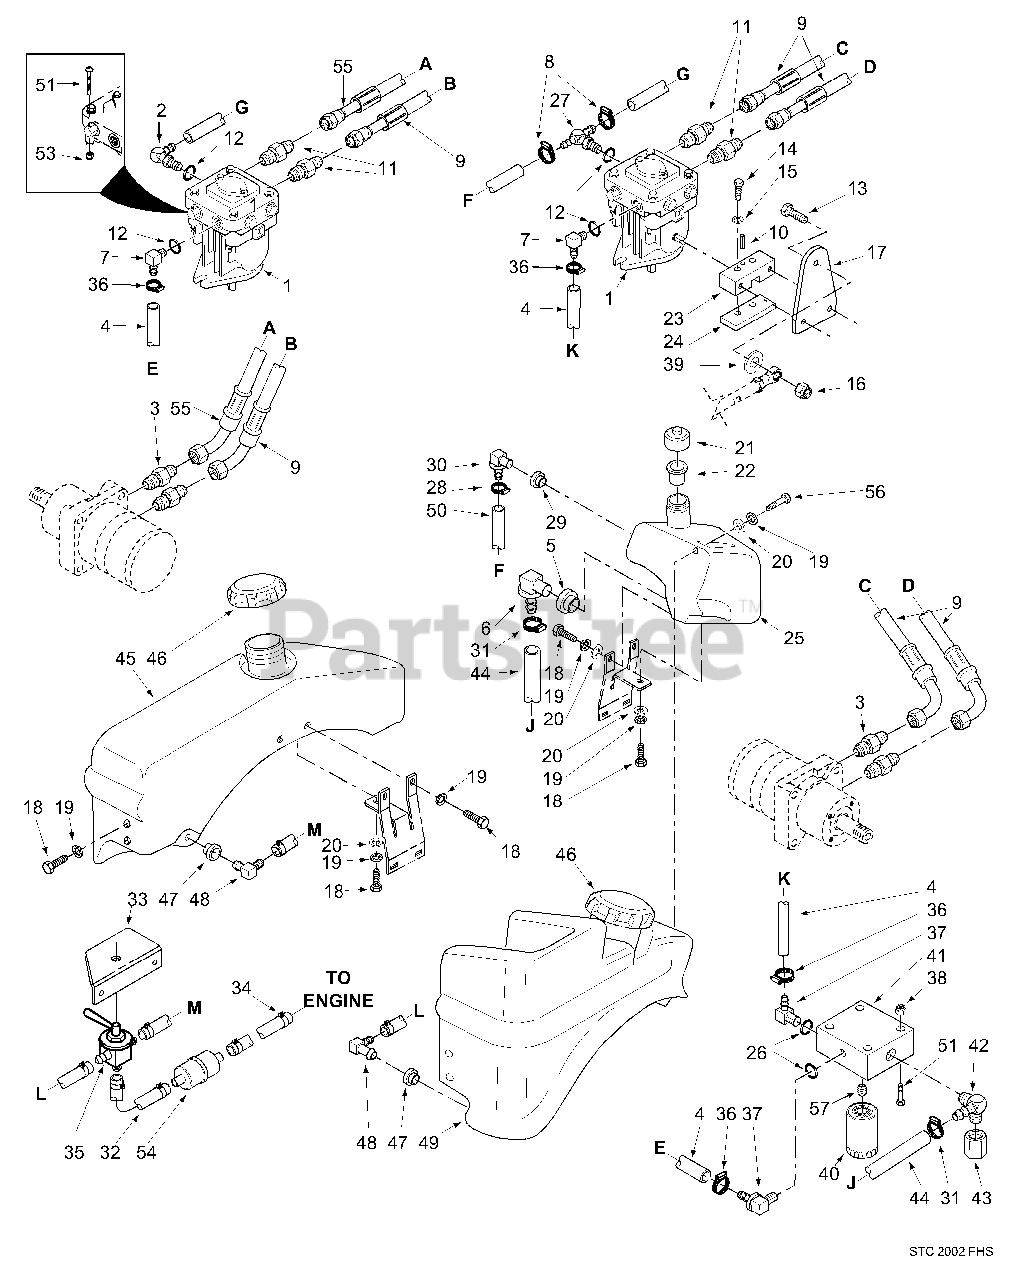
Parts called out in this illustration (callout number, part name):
1	Pump, BDP-10A-316 (L.H.)
2	Elbow, 90 Degree 9/16 O-Ring x 3/8 Hose
3	Fitting, 1/2" JIC x 5/8 O-Ring
4	Hose, 3/8 Pushlock (Specify length)
5	Bushing
6	Fitting
7	Elbow, 90 Degree 9/16 O-Ring x 3/8 Hose
8	Hose Clamp, .69 Dia.
9	Hose Assembly
10	Roll Pin
11	Fitting, 1/2" JIC x 1/2" O-Ring
12	O-Ring
13	Bolt, Hex Head 3/8-16 x 1-1/2"
14	Bolt, Hex Head 1/4-20 x 1-1/4"
15	Lockwasher
16	Nut, Elastic Stop 3/8-16
17	Control Lever
18	Bolt, Hex Head 5/16-18 x 3/4"
19	Lockwasher, 5/16
20	Flatwasher, 5/16-.375 x .875 x .083
21	Cap, Hydraulic Tank
22	Insert, Filler Neck
23	Control Block
24	Clamp Plate
25	Hydraulic Tank Assembly w/fittings
26	O-Ring
27	Tee Fitting, O-Ring to Barb
28	Clamp, .69 Max. / .25 Min. Dia.
29	Bushing
30	Elbow, 0.38 Hose
32	Fuel Hose, 1/4 ID
33	Bracket Fuel Valve
34	Clamp, Fuel Hose 1/4 Hose ID
35	Valve, Fuel Shutoff
36	Clamp, .69 Max. / .25 Min. Dia.
37	Elbow, 1/4 NTP x 3/8 Hose Barb
38	Nut, Serr. Flange 5/16-18
39	Flatwasher, 3/8-.391 x .938 x .105
40	Oil Filter
41	Filter Head Assembly
42	Fitting, Tee Special
43	Cap, 3/4-16 JIC
44	Hose, Filter Inlet
45	Fuel Tank RH
46	Cap, Fuel Tank
47	Tank Bushing
48	Elbow, 90 Degree
49	Fuel Tank LH
50	Hose, 3/8 Pushlock 15" Long
51	Bolt, Hex Head 5/16-18 x 2-1/2"
53	Nut, Elastic Stop 1/4-20
54	Fuel Filter
55	Hose Assembly
56	Bolt, Hec Head 5/16-18 x 1-1/2
57	Nipple, Oil Filter 1.0-12 UNF-2A x 1-1/4"
